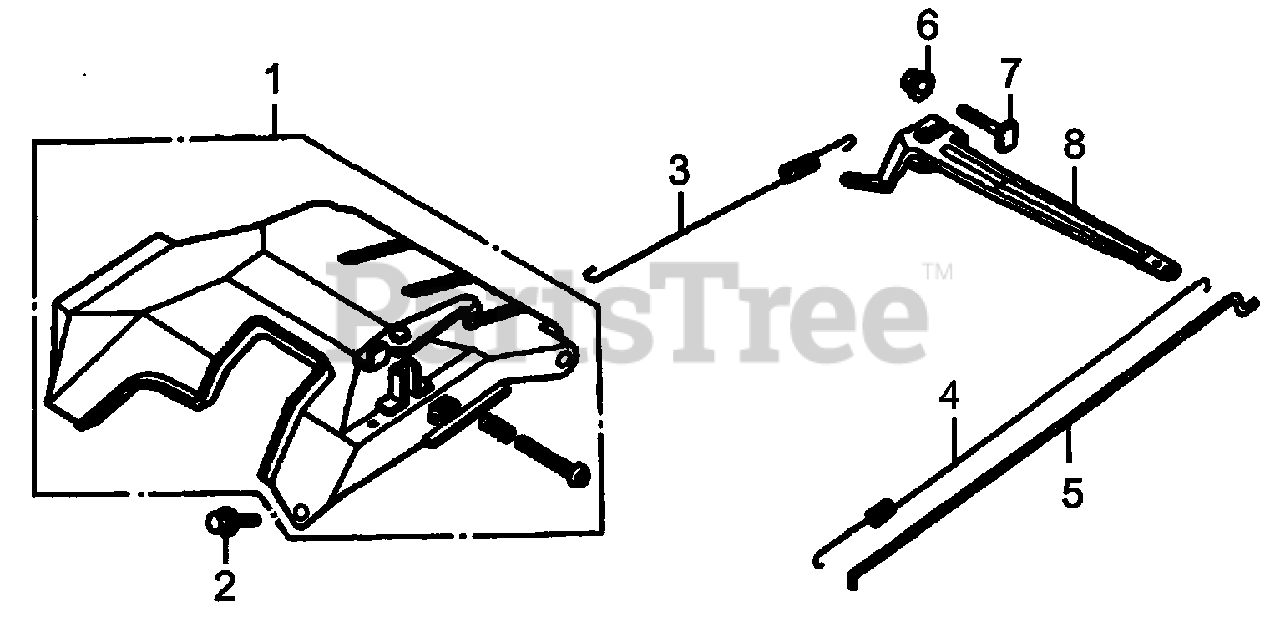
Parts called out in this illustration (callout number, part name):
1	CONTROL ASSY.
2	BOLT, FLANGE, 6×12
3	SPRING, GOVERNOR A
4	SPRING, GOVERNOR B
5	ROD, GOVERNOR
6	NUT, FLANGE, M6
7	BOLT, GOVERNOR ARM, M6X21
8	ARM, GOVERNOR
